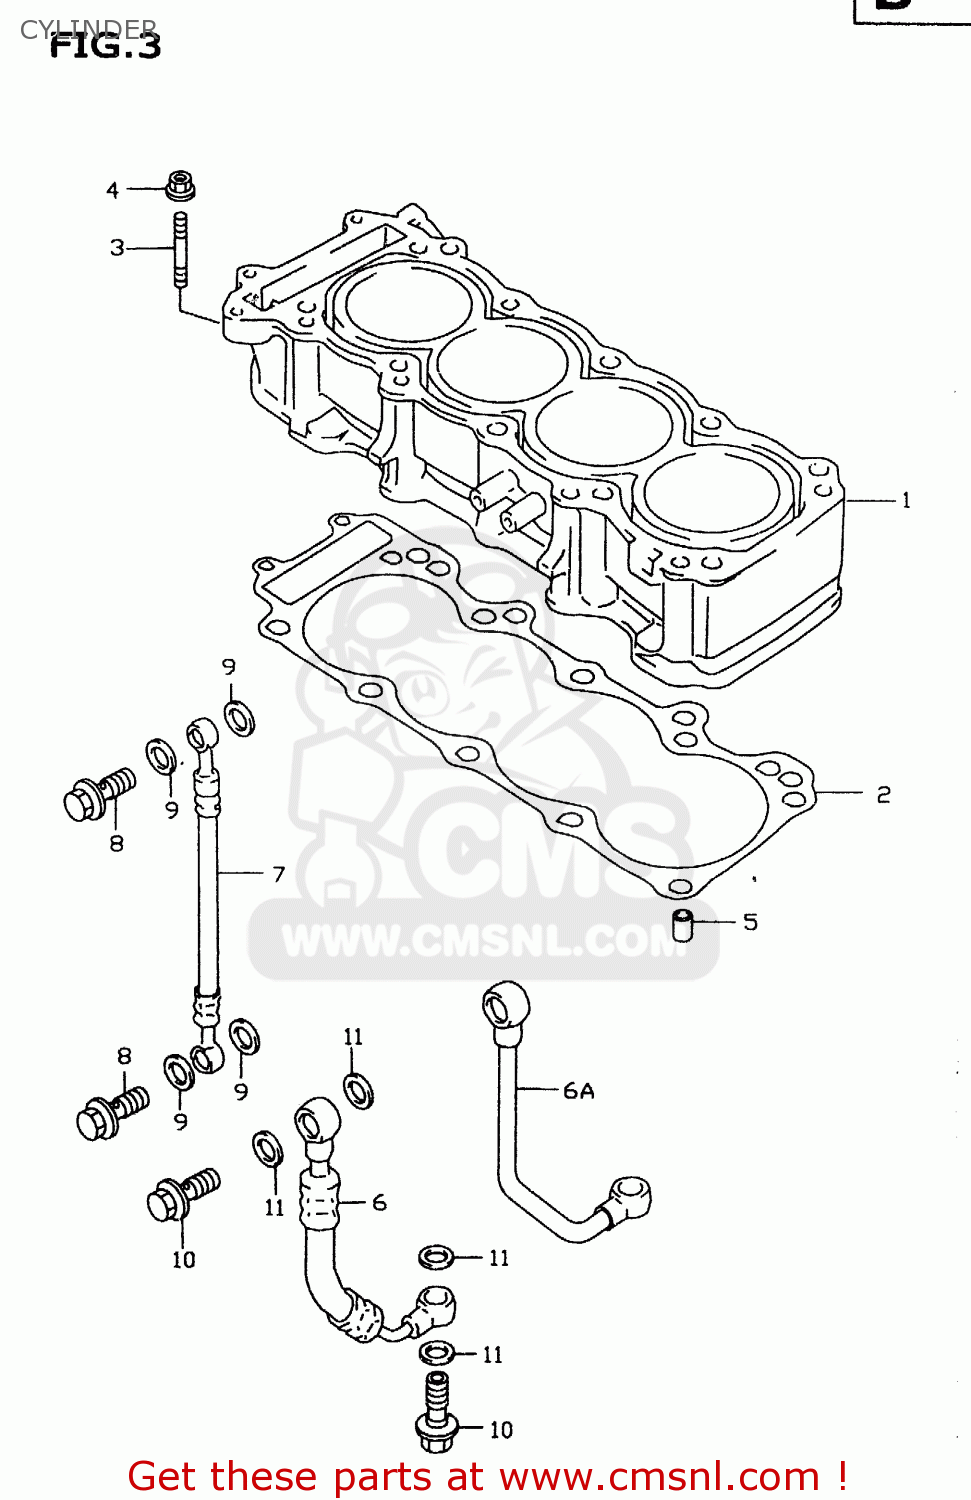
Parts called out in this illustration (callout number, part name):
1	CYLINDER
2	GASKET,CYLINDER(T:0.25)
3	STUD,M6X1X32
4	NUT
5	PIN
6	HOSE,OIL GALLERY
6A	PIPE COMP,CRANKCASE OIL
7	HOSE,CYLINDER HEAD OIL
8	BOLT UNION
9	GASKET(10.1X16X1) (NAS)
10	BOLT UNION
11	GASKET(14X20X1.5) (NAS)
